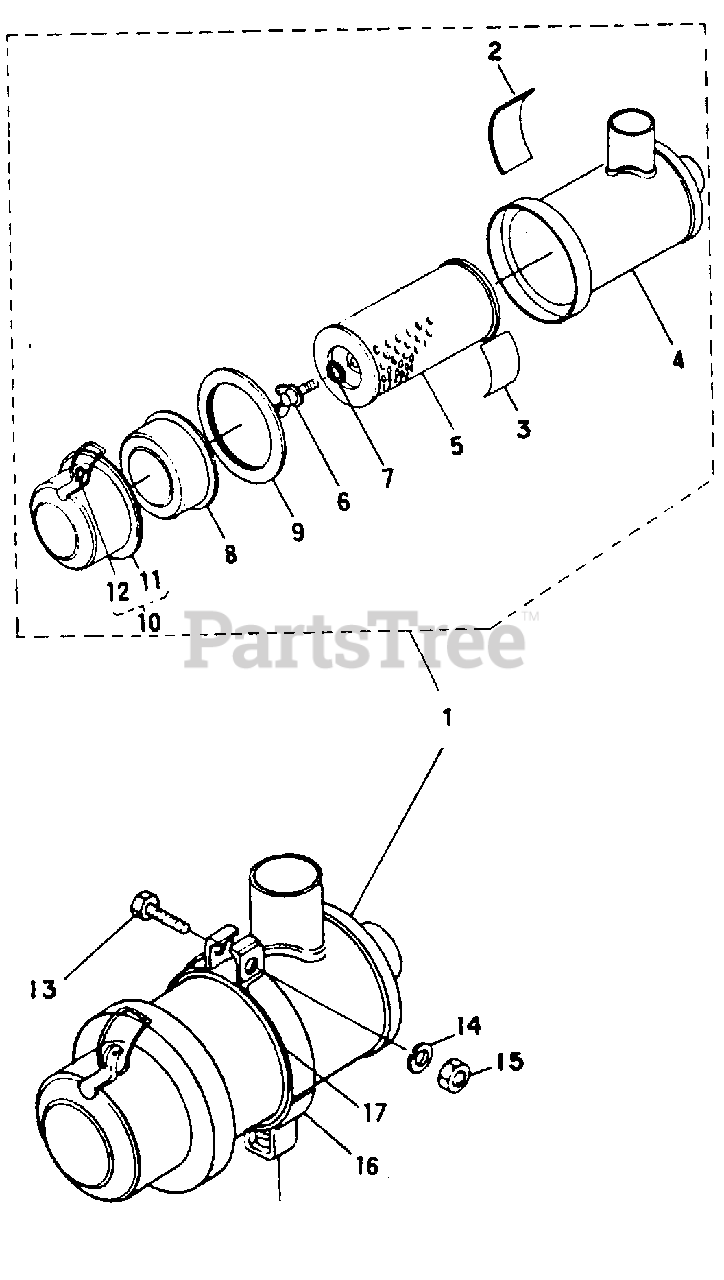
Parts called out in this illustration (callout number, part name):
1	Cleaner Assy, Air
2	Label - Not Serviced
3	Label - Not Serviced
4	Body Assy, Air Cleaner - Not Serviced Separately
5	Element, Air Cleaner
9	Gasket, Air Cleaner Cover
10	Cover, Air Cleaner
13	Bolt, M8 X 30 Pln Class 8.8
14	Washer, 8MM Lock
15	Nut, M8 Class 8
16	Band, Air Cleaner
